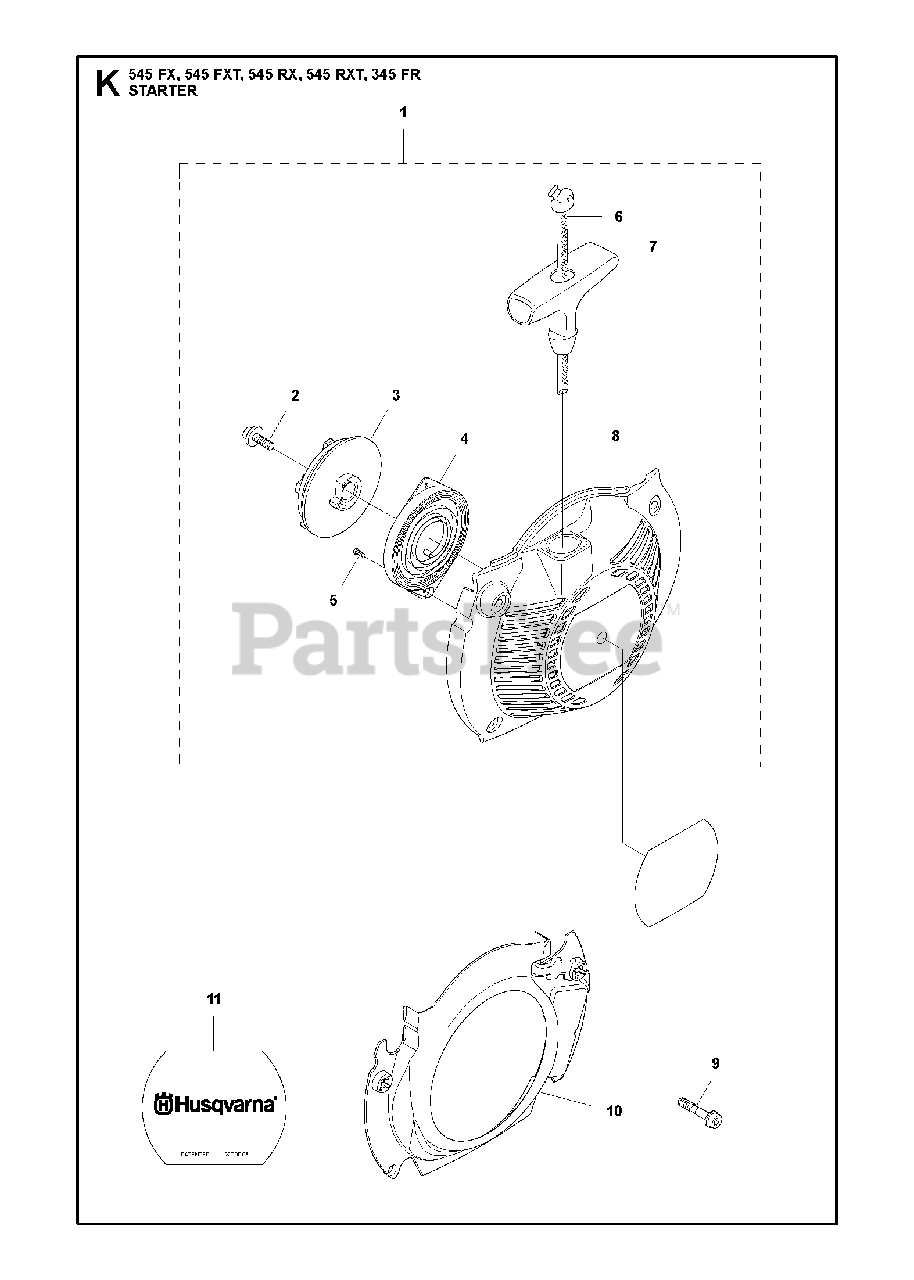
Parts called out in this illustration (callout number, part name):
2	SCREW
3	STARTER PULLEY
4	RECOIL SPRING
5	SCREW
6	STARTER ROPE
7	HANDLE
8	STARTER HOUSING
9	SCREW IHSCFMO
10	COOLING AIR CONDUCTOR
